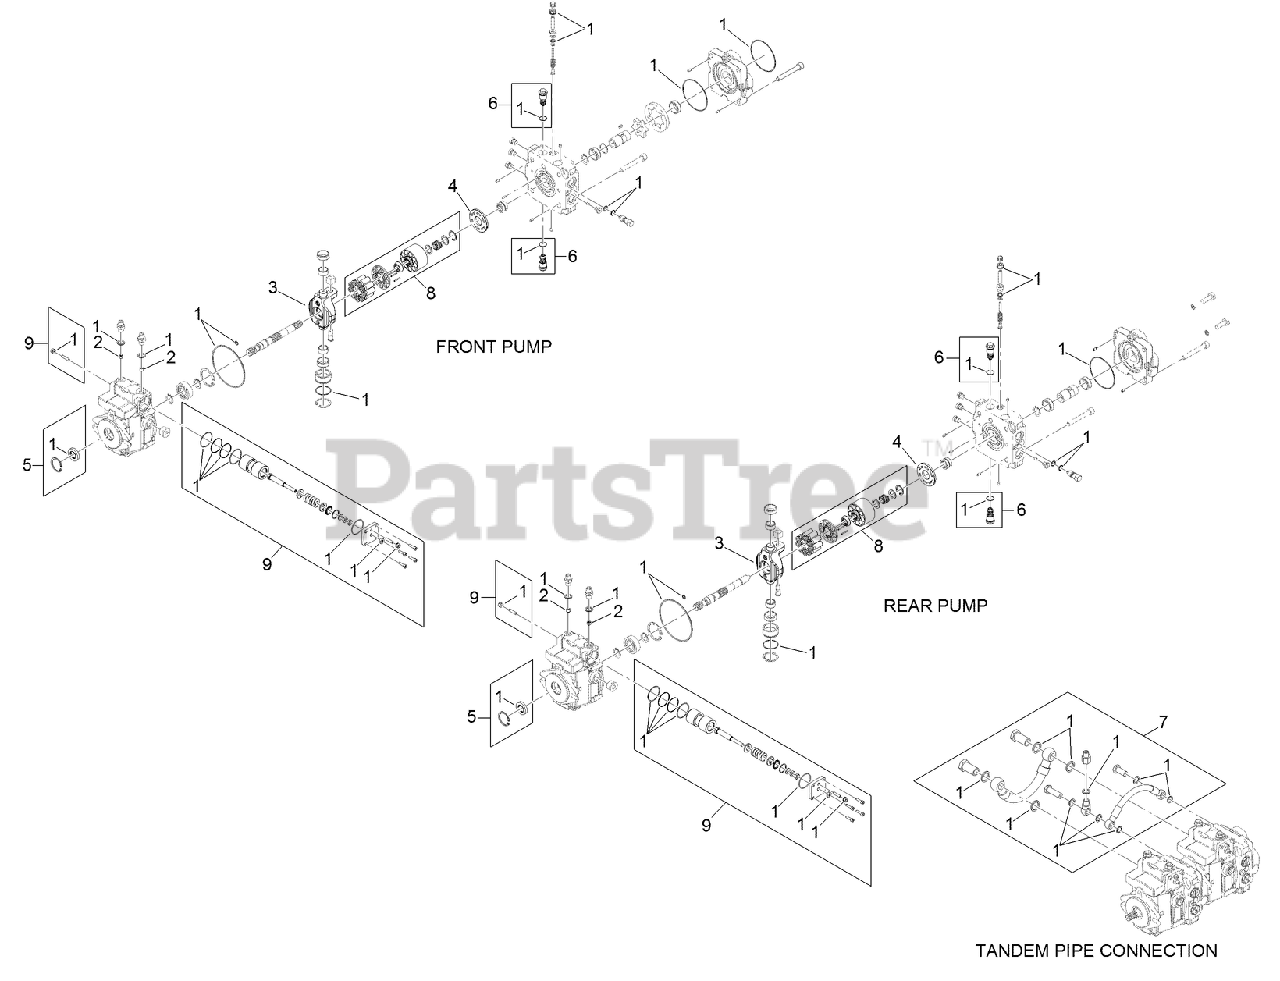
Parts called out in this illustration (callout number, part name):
1	SEAL KIT
2	SPACER-JET
3	PLATE-SWASH
4	PLATE-VALVE
5	SHAFT SEAL KIT
6	HIGH PRESSURE RELIEF VALVE KIT
7	TANDEM CONNECTION PIPE KIT
8	ROTATING GROUP KIT
9	HYD SERVO CONTROL KIT
